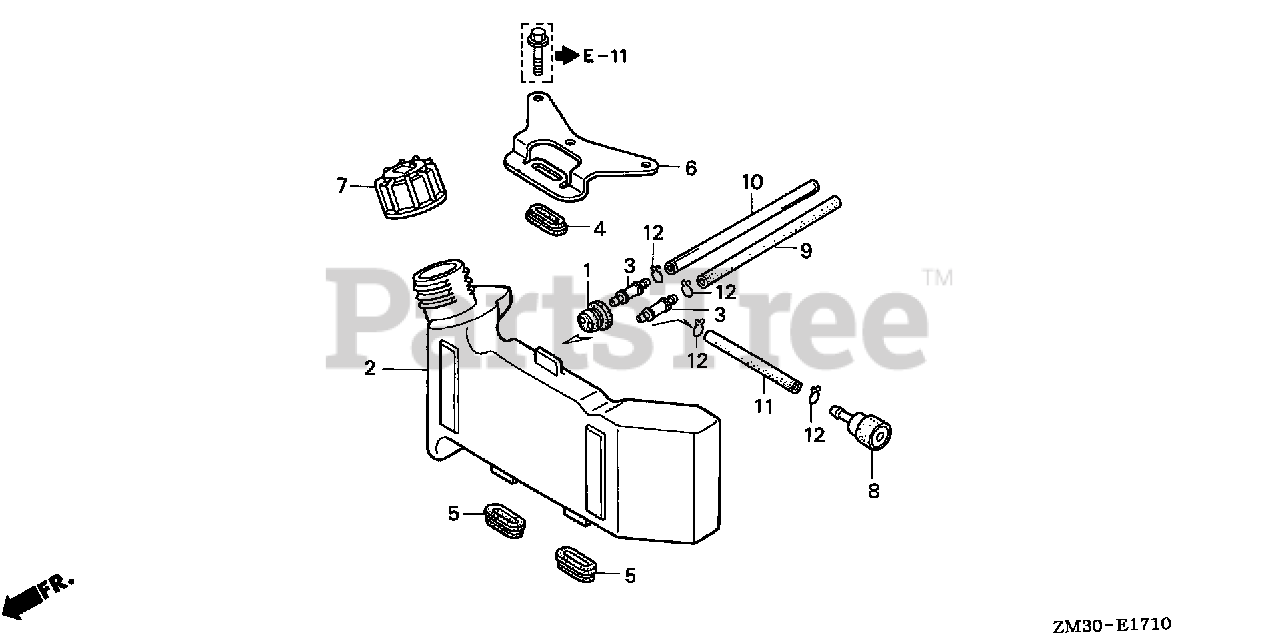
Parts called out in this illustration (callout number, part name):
1	GROMMET, FUEL TUBE
2	TANK, FUEL
4	RUBBER A, TANK MOUNTING
5	RUBBER A, TANK MOUNTING
5	RUBBER B, TANK MOUNTING
6	STAY, FUEL TANK
7	CAP ASSY., FUEL TANK
8	FILTER, FUEL
9	TUBE, FUEL
10	TUBE, FUEL RETURN
11	TUBE, FUEL
12	CLIP, TUBE
